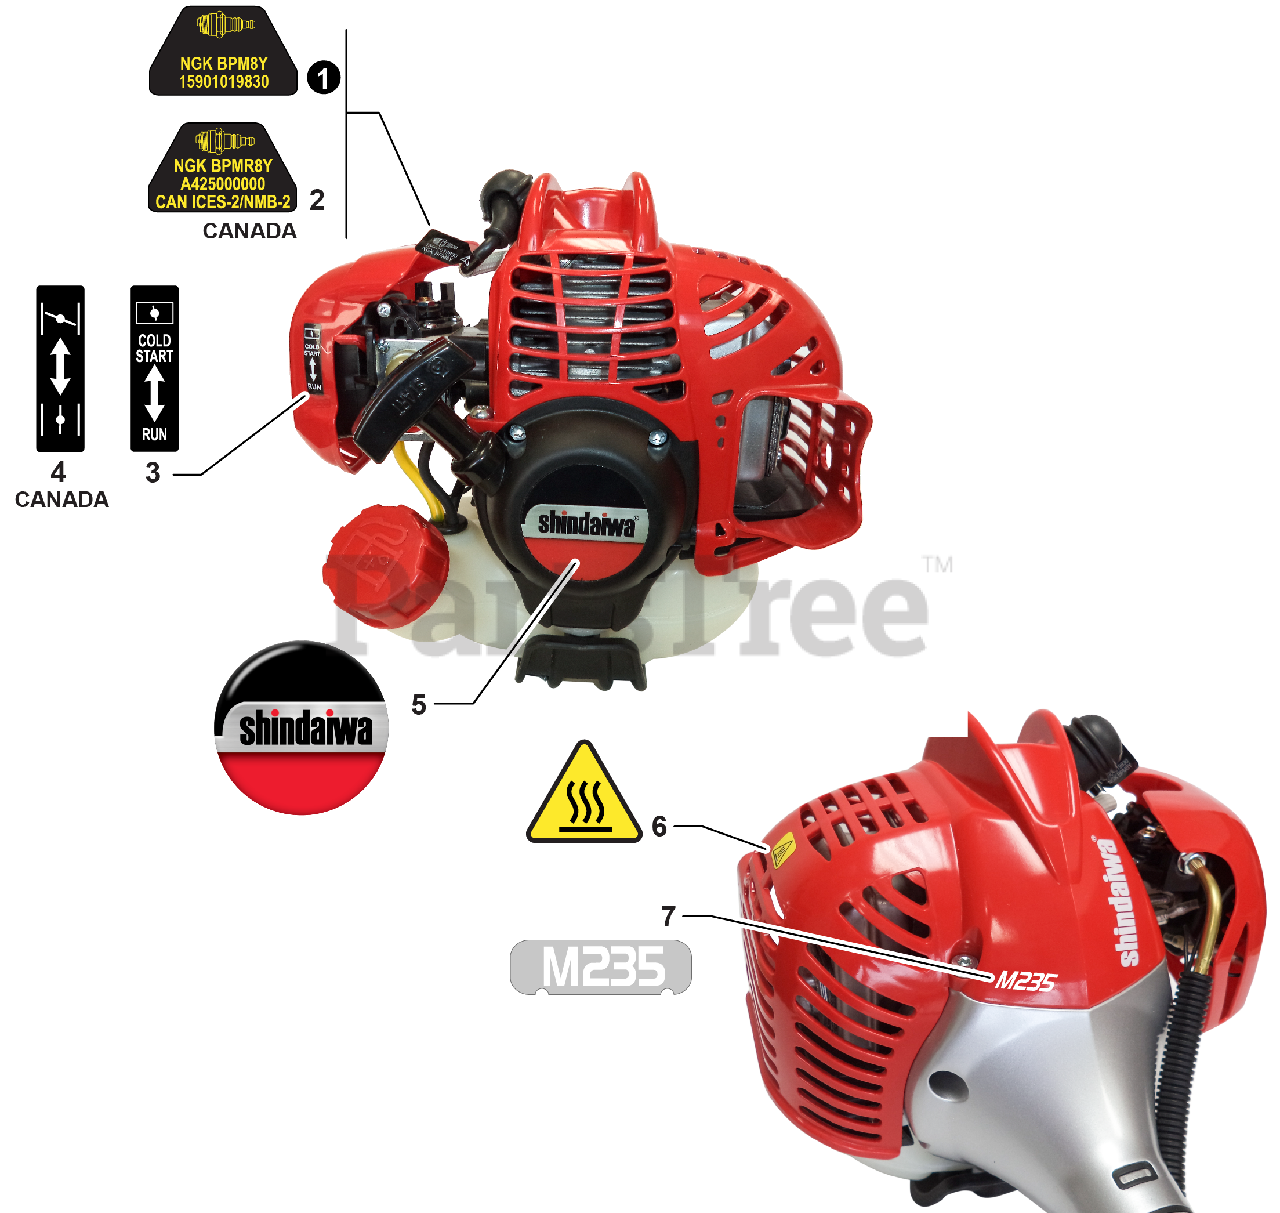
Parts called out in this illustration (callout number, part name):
1	LABEL, SPARK PLUG - BPM8Y
2	LABEL, SPARK PLUG - BPMR8Y
3	LABEL, CHOKE
4	LABEL, CHOKE
5	LABEL, SHINDAIWA
6	LABEL, CAUTION - HOT
7	LABEL - MODEL M235
